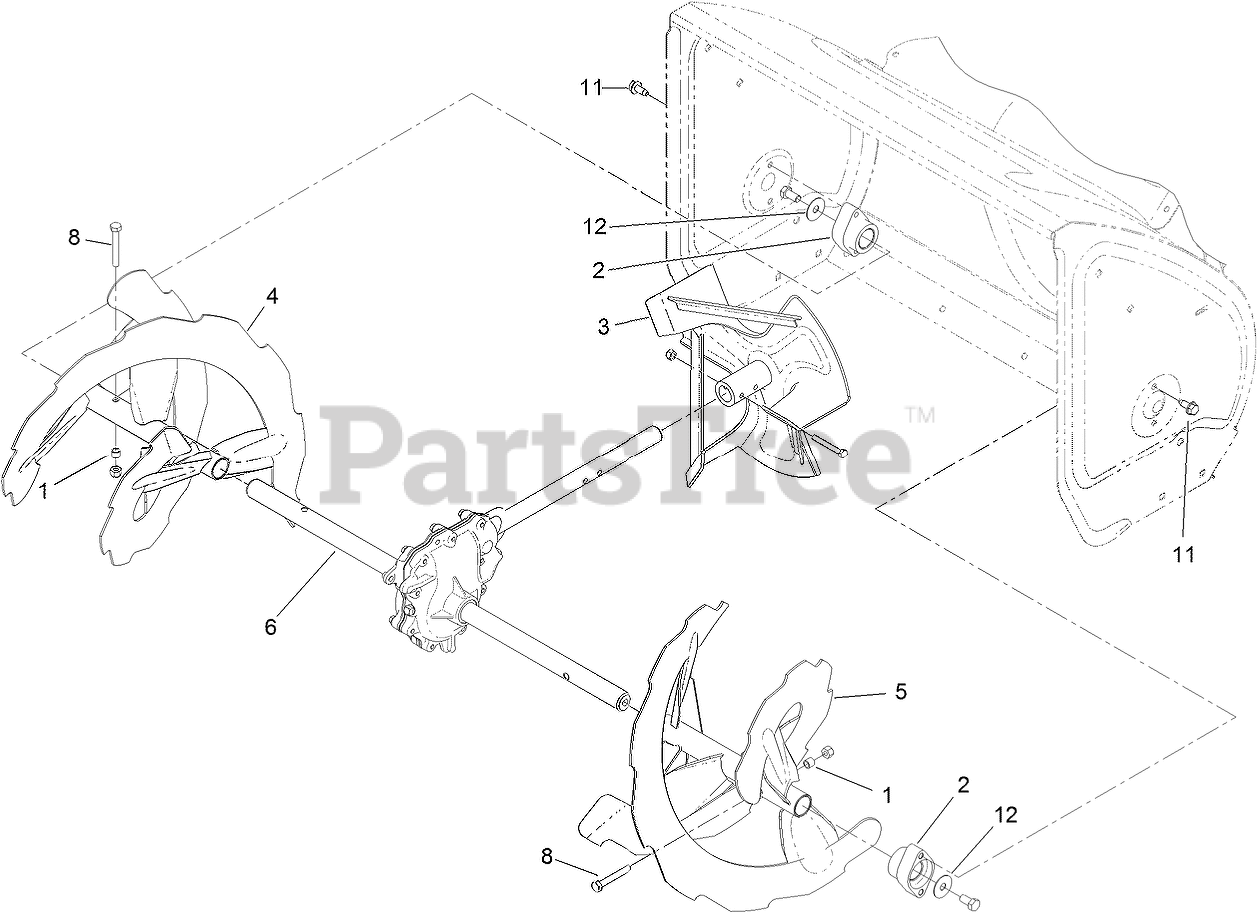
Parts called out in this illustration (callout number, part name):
1	SPACER-GROMMET
2	BEARING-AUGER
3	IMPELLER ASM
4	RH AUGER ASM
5	LH AUGER ASM
6	26 INCH AUGER GEARCASE ASM
8	SCREW-HH
11	SCREW-HWHTF
12	WASHER
